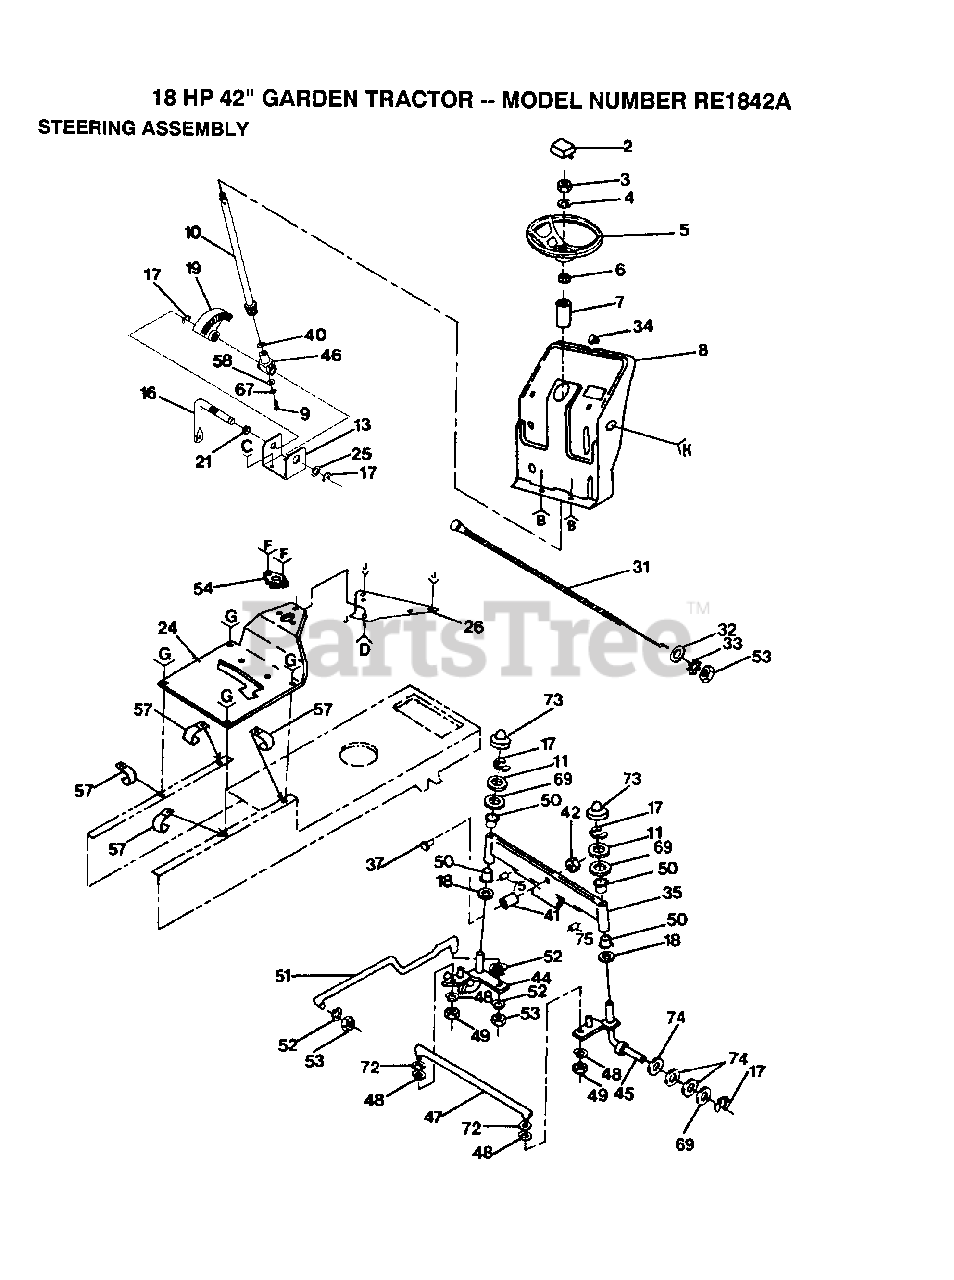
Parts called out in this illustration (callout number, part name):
2	ST WHL INSERT CAP
4	WASHER
6	ADAPTER LT
7	SLEEVE LTV
9	"SCREW,SPECIAL"
10	SHAFT&GEAR STR T
11	WASHER
13	"BRKT,STEERING"
17	RING
18	WASHER .T
21	NYLINER T
22	SCREW
25	WASHER .T
27	BOLT
31	CHOKE CONTROL
32	WASHER
33	LOCKWASHER
34	PLUG-DASH T
37	BOLT HEX 5/8-11
38	SCREW LT
40	THRUST WASHER
41	BEARING
42	"NUT-LOC,FLANGE LT"
44	SPINDLE LH
45	SPINDLE RH
46	SUPPORT.SHAFT
47	TIE ROD
48	LOCKWASHER
49	NUT.LOCK.5/16-24
50	COL. SRTG. BEAR.
52	LOCKWASHER
57	CLIP T
67	LOCKWASHER
68	NUT
69	WASHER
70	SCREW
72	WASHER M
73	CAP
74	WASHER
75	AXLE PIN
76	WASHER
77	BOLT
